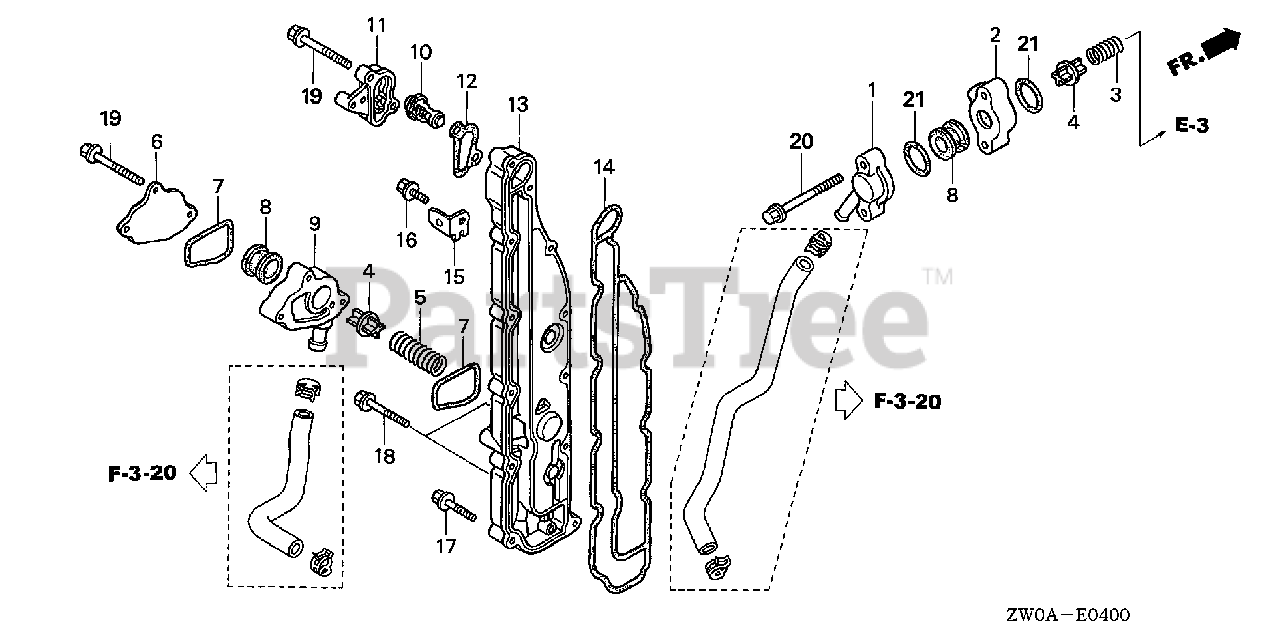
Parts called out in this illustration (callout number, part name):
1	COVER, FLUSH VALVE
2	SPACER, FLUSH VALVE *NH8* (DARK GRAY)
3	SPRING, FLUSH VALVE
4	VALVE, RELIEF
5	SPRING, RELIEF VALVE
6	COVER, RELIEF VALVE
7	GASKET, RELIEF VALVE COVER
8	GASKET, RELIEF VALVE
9	SPACER, RELIEF VALVE *NH8* (DARK GRAY)
10	THERMOSTAT ASSY.
11	COVER, THERMOSTAT
11	COVER, THERMOSTAT *NH8* (DARK GRAY)
12	GASKET, THERMOSTAT COVER
13	COVER, WATER JACKET *NH8* (DARK GRAY)
14	GASKET, WATER JACKET COVER
15	STAY A, IGNITION WIRE CLAMP
16	BOLT, FLANGE (6X12)
17	BOLT, FLANGE (6X25)
18	BOLT, FLANGE (6X32)
19	BOLT, FLANGE (6X40)
20	BOLT, FLANGE (6X55)
21	O-RING (31.5X2.4) (ARAI)
